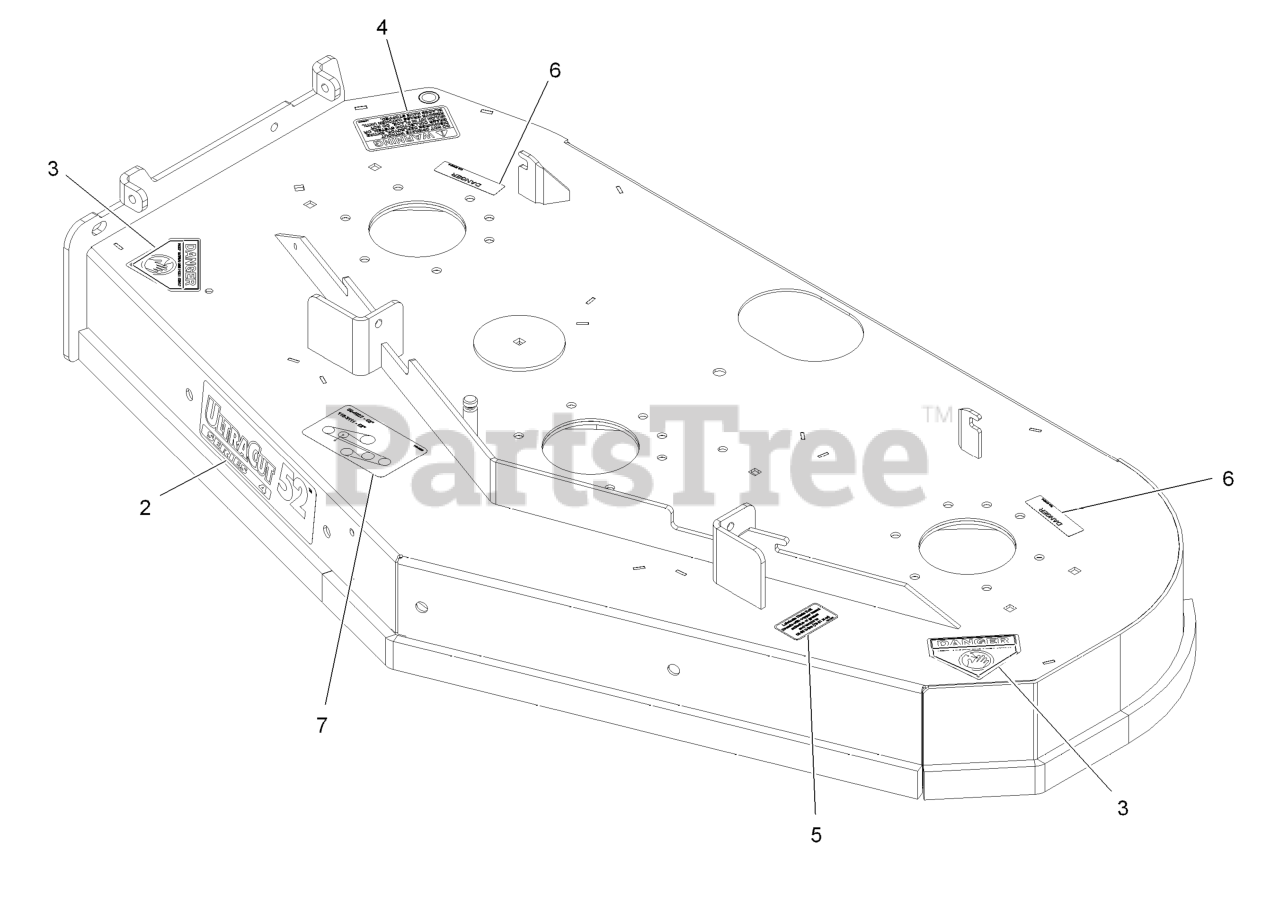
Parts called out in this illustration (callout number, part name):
2	DECAL,ULTRACUT 52 SERIES
3	DECAL-DANGER
4	DECAL-WARNING, DISCHARGE
5	DECAL,BOLT TORQUE
6	DECAL-COVER, MISSING
7	DECAL-BELT ROUTING
